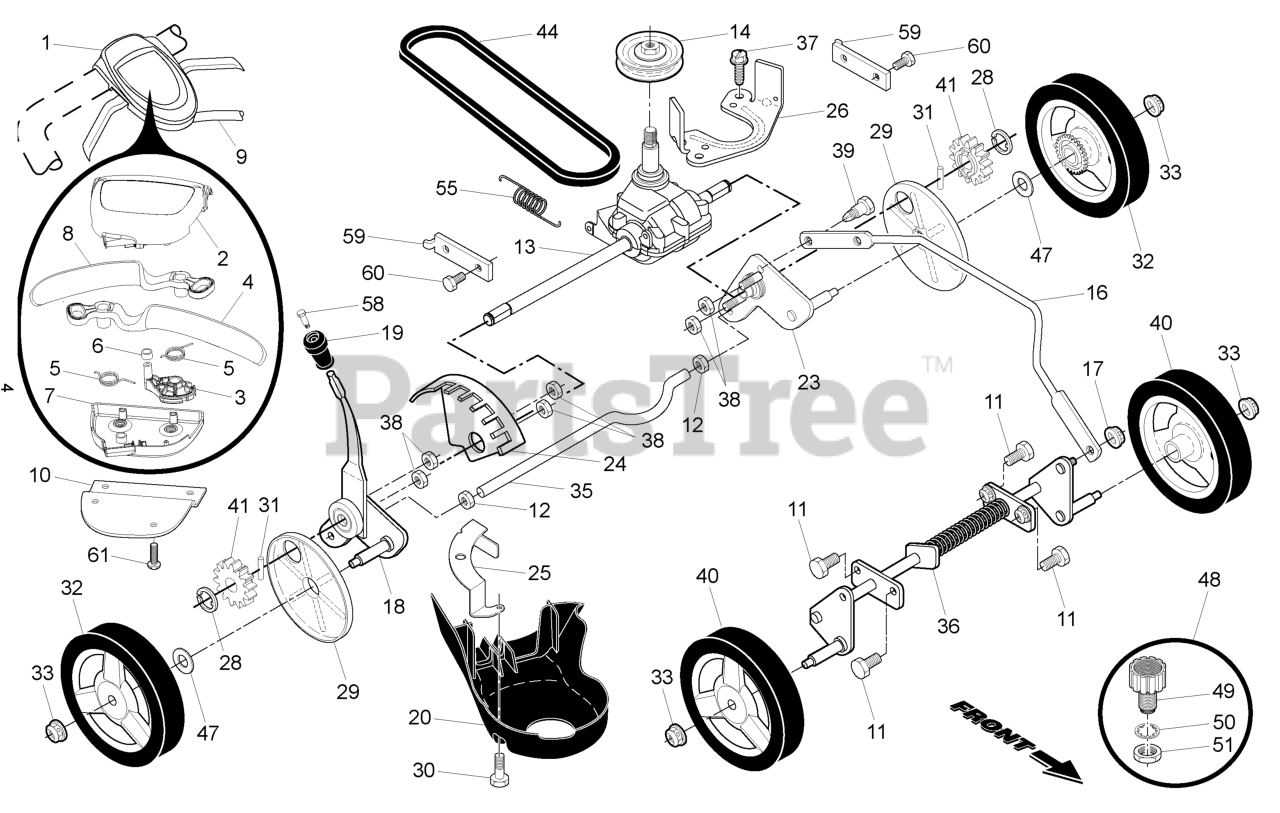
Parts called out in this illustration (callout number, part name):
1	RB CTRL.AW2.22+RGD.BS.GRY/BLK
2	RP CASE.CONT.ROL.TOP.HUSQV.
3	CAM.GEN2.DUAL.TRIGGER
4	LEVER.CONTROL.LH.22+.CURVE.BLA
5	SPRING, DRIVE CONTROL
6	BUSHING.CONTROL.CAM
7	COVER.DR.CONTROL.LOWER.GRAY
8	LEVER.CONTROL.RH.22+.CURV.BLAC
9	CABLE.CONTROL.22RGD.GEN2
10	BRACKET.DRIVE.CONTR.GEN2.BLACK
13	TRANMISSION.22+.RGD.AW
16	ROD.CONNECTING.RGD.22+.HW.BLAC
17	NUT.LOCK.5/16-18
18	SELECTOR.ASM.22+.RT.SPT LW RGD
19	KNOB.SEL.SPRING.22+.SP.RIB.BLK
20	COVER.BELT.22.RGD
23	Wheel Axle Assembly, LH
24	BRACKET.WHL.ADJ.9.POS.W/PAD
25	BRACKET.DRIVE.COVER.RGD.BZP
26	BRACKET.TRANS.BELT.KEEPER.BZP
28	E-RING 7/16 RE
29	COVER.DUST.WHEEL
30	BOLT.HEX.HD.WASHER.5/16-18X.75
31	PAWL, DRIVE
32	WHEEL & TIRE ASSY, REAR
33	NUT.HEX.FLANGE.3/8-16.LO(3 2)
35	AXLE.REAR.RGD
36	AXLE.ASM.FRONT.RGD.BZP
38	NUT.HEX.FLANGE.1/4
39	SHOULDER BOLT SEMI GIMLET PT.
40	WHEEL & TIRES ASSY, FRONT
41	PINIION.14.TOOTH.RGD
44	BELT.DRIVE.RGD.PLUS
47	WASHER FLUT
48	KIT.WASH-OUT.PORT
49	FITTING, HOSE, WATER WASHOUT
50	WASHER.LOCK.INTERNAL.TOOTH
51	LOCKNUT.HEX.WITH.O-RING
58	BOLT.HEX.HD.WASHER.5/16-18X.75
59	BRACKET.SUPPORT.22+.RWGD.BZP
60	BOLT.HEX.HD.WASHER.5/16-18X.75
61	SCREW, PHILLIPS HEAD 10 X 5/8
